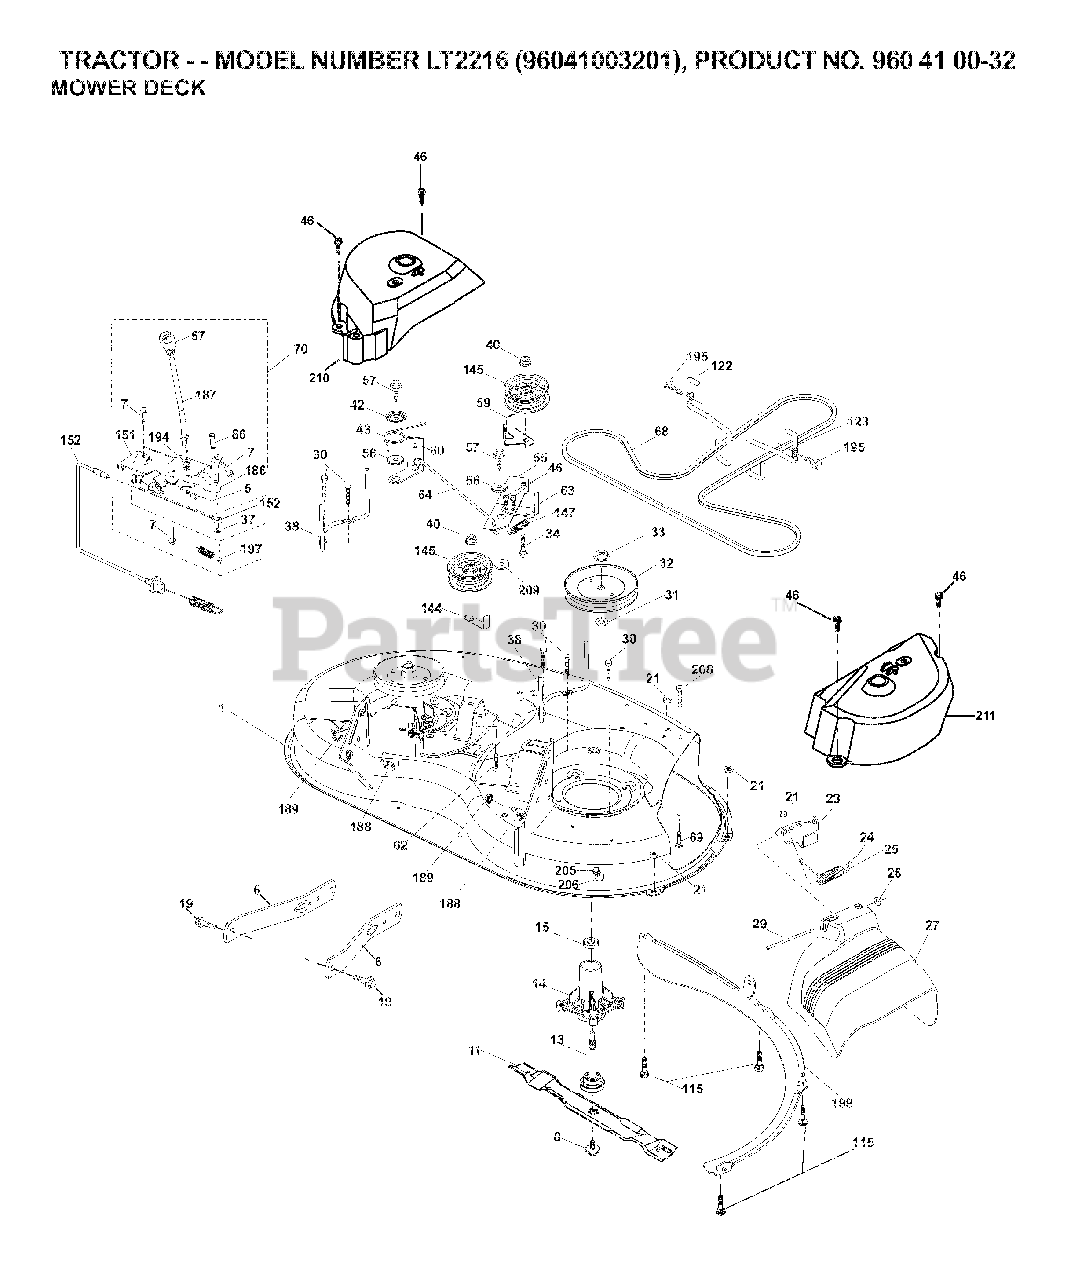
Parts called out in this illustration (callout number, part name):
6	ARM.SUSPENSION.MOWER.R
7	SCREW.#10 X 0.750.BOS THREAD
8	BOLT.WASHER.ASM.7/16-2
11	BLADE 38" PREMIUM
13	SHAFT.ASM.MDRL.N/GREASE.38
14	HOUSING MANDREL
19	BOLT.SHOULDER
21	LOCKNUT
23	BRKT.DEFLECTOR.38"2005+
24	CAP-SLEEVE LT
25	SPRING.TORSION.DEFLECT
26	NUT PUSH M
29	ROD.HINGE
30	SCREW, WASHER HEAD
31	WASHER.SPACER.MANDREL
32	PULLEY.MANDREL.5.0.PD.38"
33	NUT.FLANGE.LOCK.TOP
34	BOLT.3/8-16X1.50
38	KEEPER BELT LH MANDREL
40	NUT LOCK FLG 3/8-16 UNC
42	SPRING.TORSION.BRAKE
43	SRPING.TORSION.RETAINE
46	SCREW.1/4-20X5/8
55	IDLER.ARM
56	SPACER.RETAINER
57	SCREW 3/8-16X1
59	GUARD, BELT
60	ARM BRAKE MOWER RH 38"
62	BOLT.3/8-16X1.50
63	ARM BRAKE MOWER RH
64	LINK BRAKE
67	HANDLE.CLUTCH.CABLE.LT
69	BOLT
70	CLUTCH.ASM.MANUAL.LT.TEX
115	BOLT
122	KEEPER BELT ENGINE LH
123	KEEPER BELT RH
144	KEEPER, BELT IDLER
145	PULLEY.IDLER.48"PRIMARY
147	SPRING RETURN
152	CLUTCH CABLE
188	STUD.FASTNER.W/ANTI-ROTATE
189	NUT LOCK HEX FLANGE 5/16-18
195	SCREW, 3/8-16X3/4
199	BAFFLE VORTEX
205	SCREW
208	SCREW 3/8-16X1/2
209	WASHER 12/32X2X10GA
